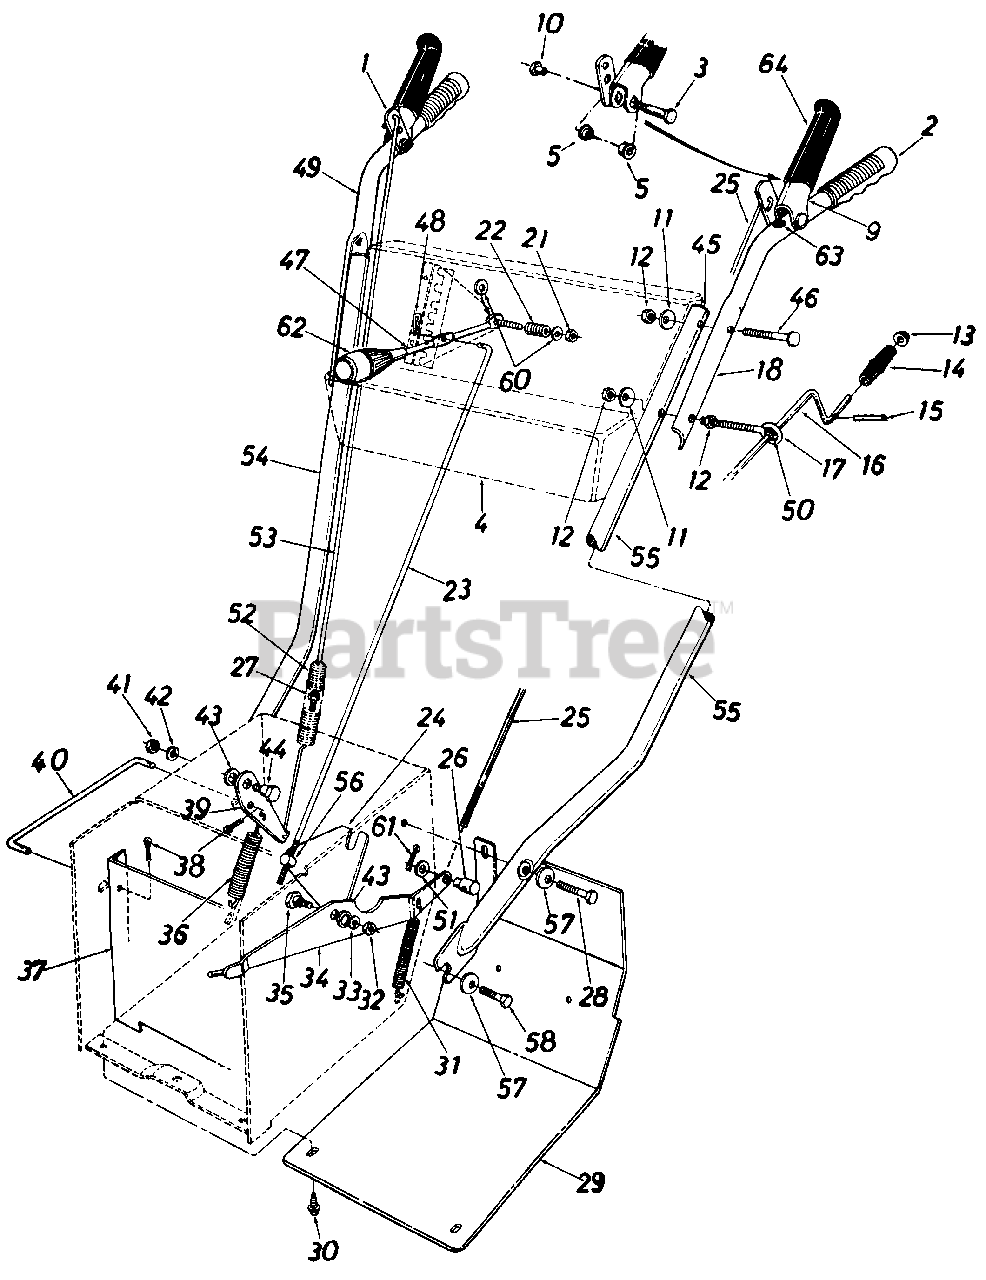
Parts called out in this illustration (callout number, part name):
1	Clutch Grip Ass'y.-R.H.
2	Grip-Red
3	Shoulder Bolt .374 Dia. x 1.375" Lg.
4	Handle Panel Ass'y.
5	Hex Flange Plastic Bearing .380" I.D.
9	Clutch Grip Ass'y.-L.H.
10	Shoulder Nut 1/4-20 Thd.
11	Bell-Wash. .34" I.D. x .88" O.D.
12	Hex Nut 5/16-18 Thd.
13	Push Nut 3/8" Rod
14	Knob 3/8" Rod
15	Roll Pin .12 Dia. x .63" Lg.
16	Chute Crank Ass'y. 39" Lg.
17	Eye Bolt 5/16-18 x 5.0" Lg.
18	Upper Handle-L.H. (Painted)
21	Hex Ins. Jam L-Nut 5/16-18 Thd.
22	Compression Spring .50" O.D. x .88" Lg.
23	Shifting Rod 5/16" x 32.50" Lg.
24	Shifting Linkage Bracket
25	Lockout Rod .214" Dia. x 36.0" Lg.
26	Adjustment Ferrule 1/4-20
27	Hex Ins. L-Nut 1/4-20 Thd.
28	Hex Bolt 3/8-16 x 2.00" Lg.
29	Frame Cover
30	Hex Wash. Self-Tap Scr. 1/4-20 x .50" Lg.
31	Extension Spring .38" O.D. x 3.25" Lg.
32	Hex Jam Nut 3/8-16 Thd.
33	L-Wash. 3/8" I.D.
34	Auger Clutch Bracket Ass'y.
35	Shld. Bolt .625 Dia. x .170
36	Extension Spring .75 O.D. x 4.31 " Lg.
37	Drive Pulley Support Brkt. Ass'y.
38	Cotter Pin 3/32' Dia. x .75" Lg.
39	Drive Clutch Bracket
40	Drive Clutch Rod
41	Hex Jam Nut 3/8-16 Thd.
42	L-Wash. 3/8 I.D.
43	Bell-Wash. .40 I.D. x 1.13" O.D.
44	Shld. Bolt .625 Dia. x .170
45	Plastic Plug
46	Carriage Bolt 5/16-18 x 2,0n Lg.
47	Shift Handle
48	Int. Cotter Pin 5/16" Dia.
50	Plastic Bushing
51	Fl-Wash. .344n I.D. x .62 O.D.
52	Extension Spring .75 O.D. x 5 oon Lg.
53	Lockout Rod .214' Dia. x 32" Lg.
54	Lower Handle-R.H. (Painted)
55	Lower Handle-L.H. (Painted)
56	Adjustment Ferrule
57	Bell-Wash. .40 I.D. x .88 O.D.
58	Hex Wash. Self-Tap Scr. 3/8-16 x .75" Lg.
60	Fl-Wash. .344 I.D. x .62 O.D.
61	Cotter Pin 8/32" Dia.
63	Push Cap
64	Black Vinyl Grip
